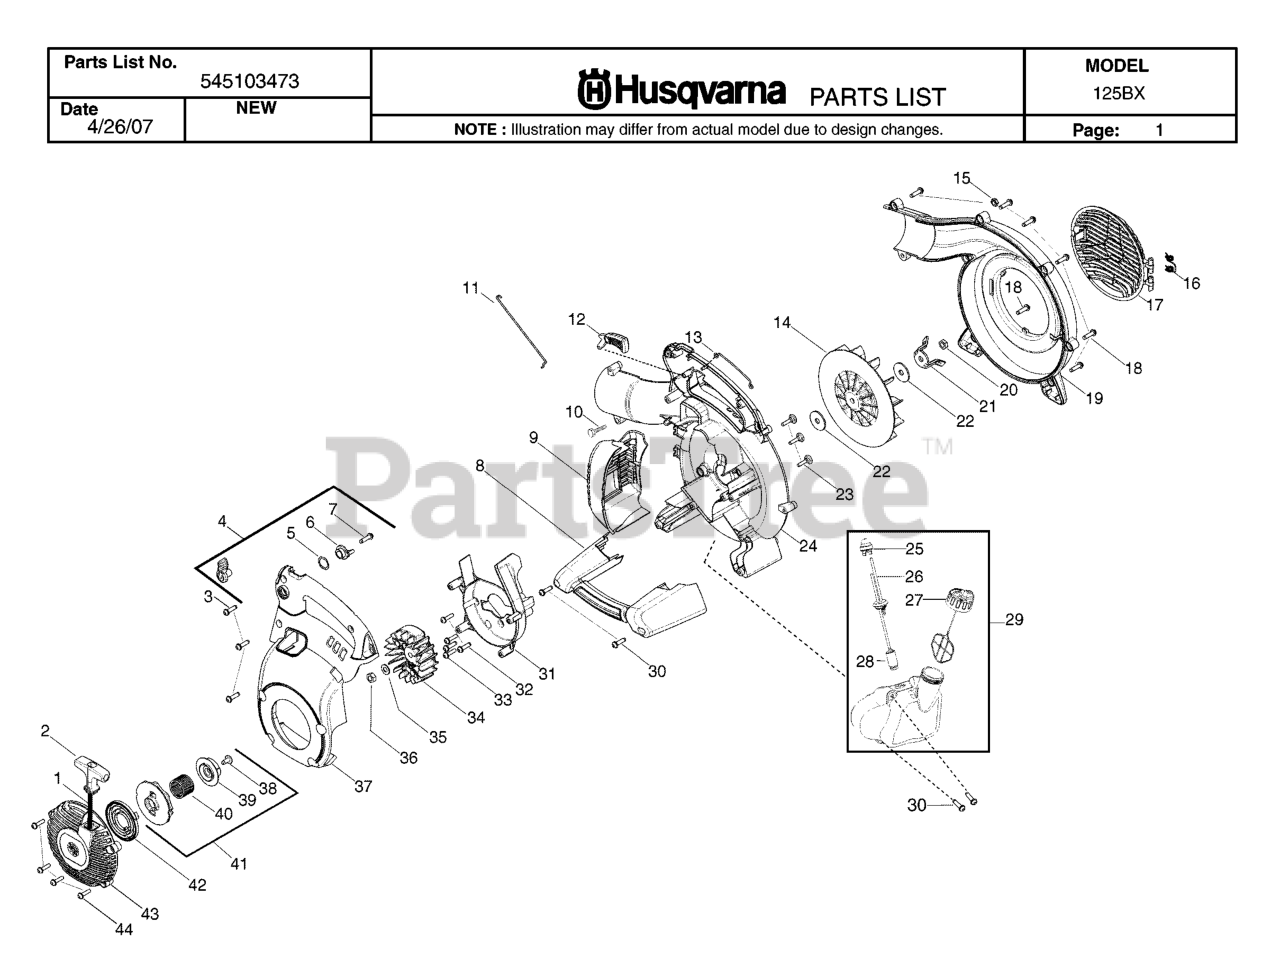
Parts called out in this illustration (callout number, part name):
2	STARTER HANDLE GRAY
4	KIT CRUISE CONTROL
5	WAVE WASHER
6	RATCHET CRUISE CONTROL
8	HANDLE ASSIST W/OVER MOLD
9	ASSY, MUFFLER GUARD
10	ASSY, BLOWER KNOB
11	WIRE LINKAGE
12	TRIGGER, THROTTLE
13	WIRE, HANDLE GROUND
14	IMPELLER
16	SPRING, VAC DOOR
17	COVER VAC DOOR
19	ASSY - OUTER SCROLL
20	NUT, IMPELLER
21	BLADE - MULCH
22	WASHER, IMPELLER
23	SCREW FUEL TANK RETAINER
24	SCROLL - INNER
26	FUEL LINE GROMMET KIT
27	ASSY-CAP W/RETAINER
28	FUEL PICK-UP ASSY
29	ASSY, FUEL TANK
31	SCROLL, FLYWHEEL
33	SCREW - SHROUD
34	ASSY, FLYWHEEL
35	WASHER FLAT
36	NUT-FLYWHEEL
37	COVER - MOTOR HOUSING
40	SPRING EPS2
41	KIT - STARTER
42	SPRING STARTER
43	HOUSING - STARTER COVER
44	SCREW - SHROUD
